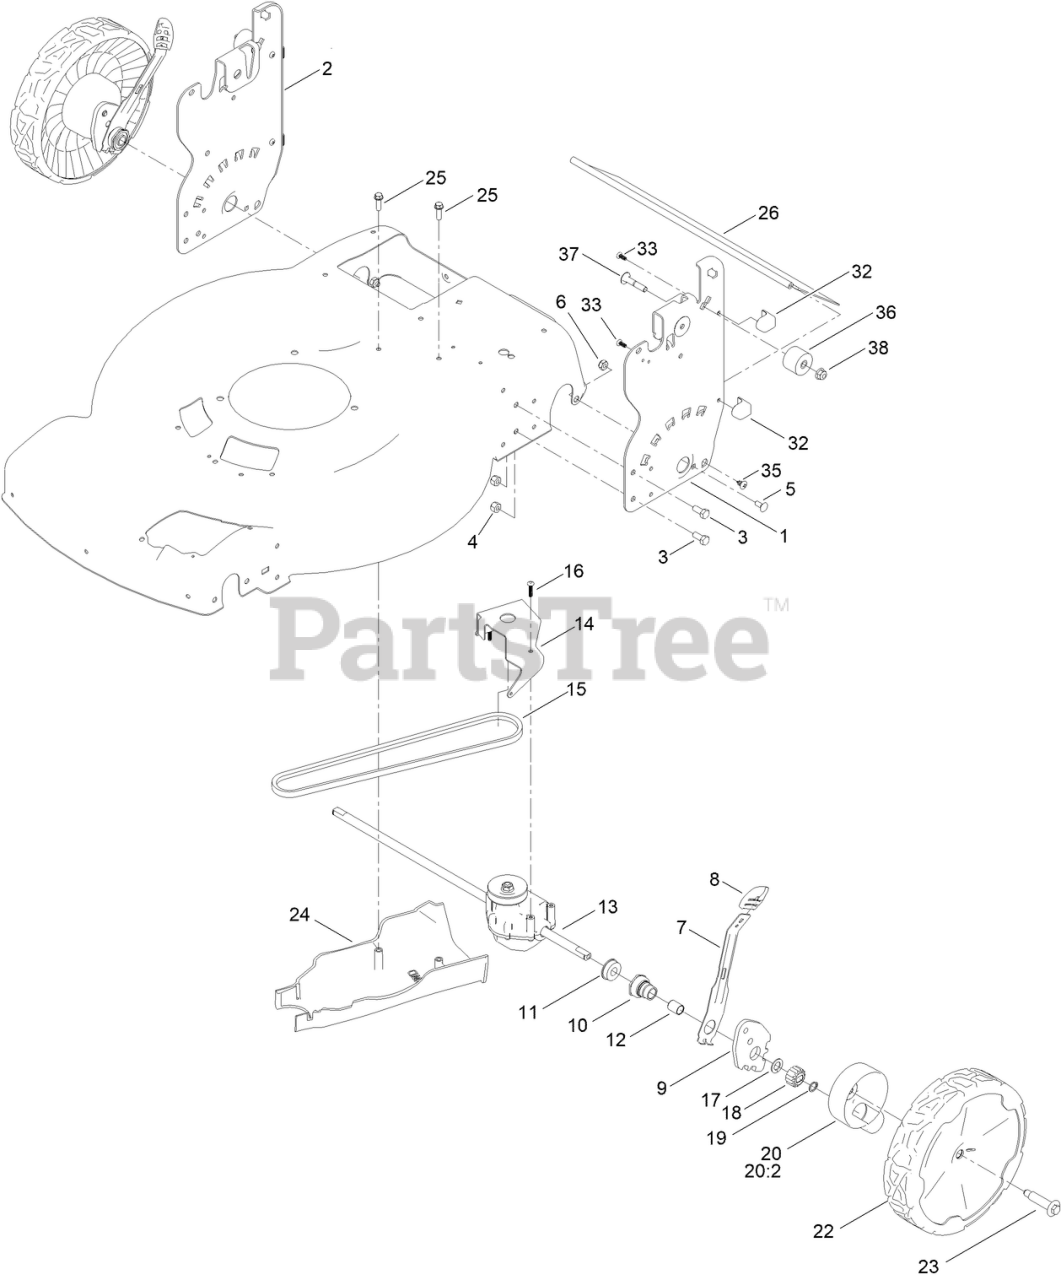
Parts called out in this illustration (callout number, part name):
1	PLATE-HOC, LH (ISO)
2	PLATE-HOC, RH (ISO)
3	SCREW-HH
4	NUT-LOCK, NI
5	SCREW-CARR
6	NUT-LOCK, NI
7	ARM-SPRING
8	KNOB-LEVER, HOC
9	ARM-PIVOT, REAR
10	RETAINER-BUSHING, HOC
11	BEARING-BALL
12	BUSHING-SLEEVE
13	TRANSMISSION-RWD
14	BRACKET-TRANSMISSION
15	V-BELT
16	SCREW-PLASTITE
17	WASHER-THRUST
18	GEAR-PINION, 15T
19	RING-RETAINING
20	ASM-COVER, GEAR (DK GRAY)
20:2	WASHER-STEPPED
22	ASM-9.65" WHEEL, GEARED
23	WHEEL BOLT
24	COVER-BELT, RWD
25	SCREW-HWH
26	SHIELD-TRAILING
32	PAD-SMART STOW
33	SCREW-PLASTITE
35	SCREW-THD
36	BUMPER-ISOLATOR
37	SCREW-CARR-SPCL
38	NUT-HF, NI
